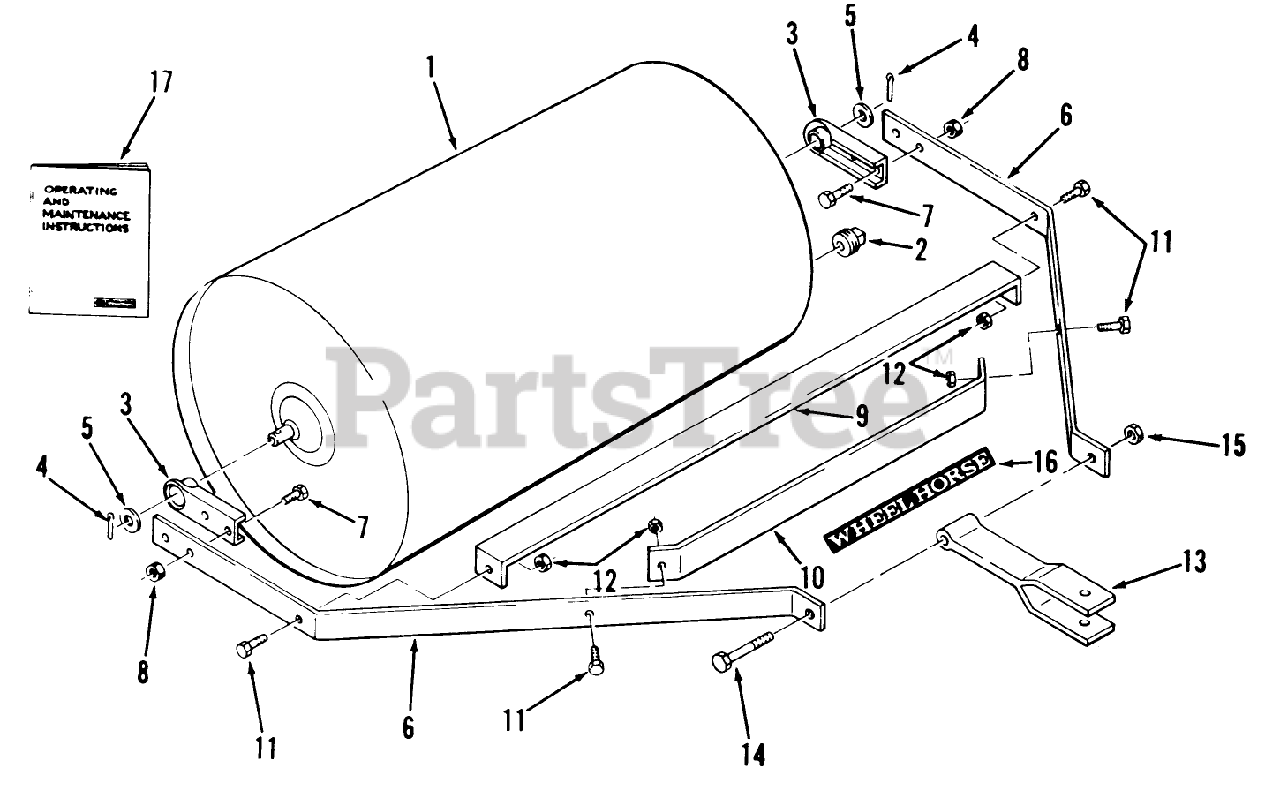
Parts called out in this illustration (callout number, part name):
1	Drum Assembly
2	Pipe Plug
3	Hub (w/Bushing)
4	Pin-Cotter
5	WASHER
6	Frame Side Bar
7	Bolt
8	Nut
9	Scraper Bar
10	Frame Support
11	BOLT
12	NUT
13	HITCH ASSEMBLY
14	Bolt 1/2-13 x 3 1/2
15	Nut
16	DECAL-WHEEL HORSE
17	Operating and Maintenance Instructions
